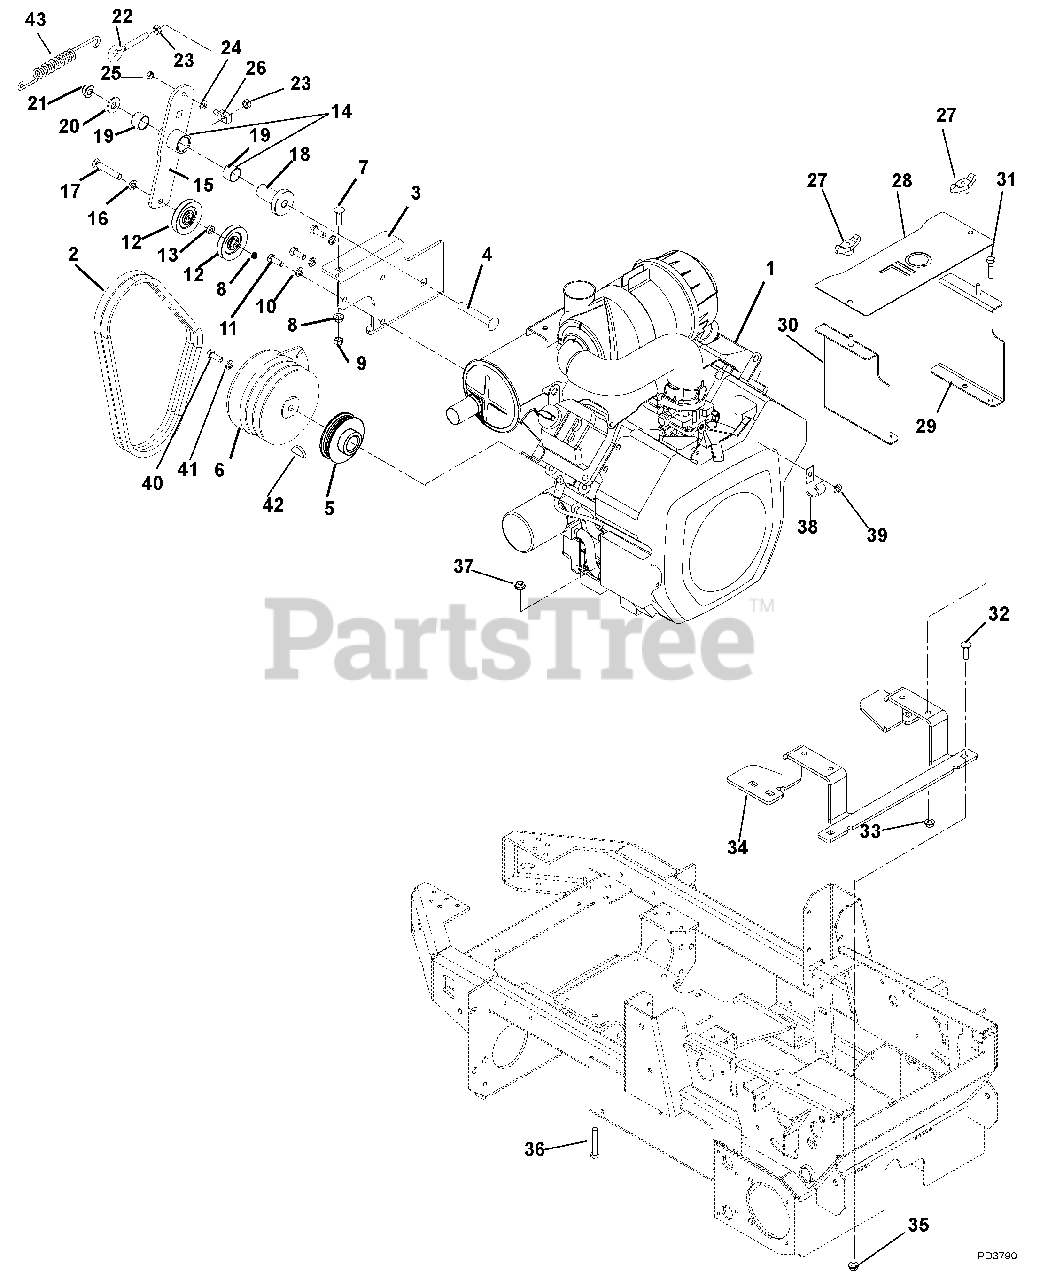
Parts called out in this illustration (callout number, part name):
1	Engine, 27hp Kohler (990100)
2	Belt,B 41.313 Matched Set
3	Bracket, PTO Idler Mounting
4	Bolt, Round Head Square Neck .50-13 x 3.50 Grade 5
5	Sheave, Poly-V
6	Clutch, Warner Double Groove
7	Bolt, Round Head Square Neck .38-16 x 1.25 Grade 5
8	Nut, .38-16 Nyloc Flange
9	Nut, Locking-Center .38-16
10	Washer, Locking .38 x .094 Regular
11	Bolt, Hex .38-16 x 1.00 Grade 5
12	V-Idler, 4.00 x .38
13	Washer, .406 x 1.0 x .38THK
14	Assembly, Idler Pivot Assembly (includes items 15 and 19)
15	Weldment, PTO Idler Pivot Arm (OFM)
16	Washer, Flat-Steel .438 x 1.00 x .083
17	Bolt, Hex .38-16 x 3.00 Grade 5
18	Bearing, Pedestal
19	Bearing, 1.00 x 1.12 x .75
20	Washer, Flat-Steel .531 x 1.250 x .100
21	Nut, .50-13 Nyloc Flange
22	Bolt, Eye .375-16 x 2.50
23	Nut, Hex .38-16
24	Washer, Flat-Steel .344 x .688 x .065
25	Nut, Locking Center .31-18
26	Pin, Pivot
27	Knob, Wing
28	Shroud, Cooling
29	Bracket, Tank Shroud Left Hand
30	Bracket, Tank Shroud Right Hand
31	Bolt, Hex .38-16 x 1.50 Grade 5
32	Bolt, Round Head Square Neck .38-16 x 1.00 Grade 5
33	Nut, .38-16 Nyloc Flange
34	Mount, Hydraulic Tank
35	Nut, .38-16 Nyloc Flange
36	Bolt, Hex .38-16 x 2.25 Grade 5
37	Nut, Locking-Top-Flange .38-16
39	Washer, Flat-STL.281 x .62 x .065
40	Bolt, Hex .44-20 x 2.25 Grade 5 EP80
41	Washer, Locking .44 x .109 Regular
43	Spring-Tension .135X.69X5.75
